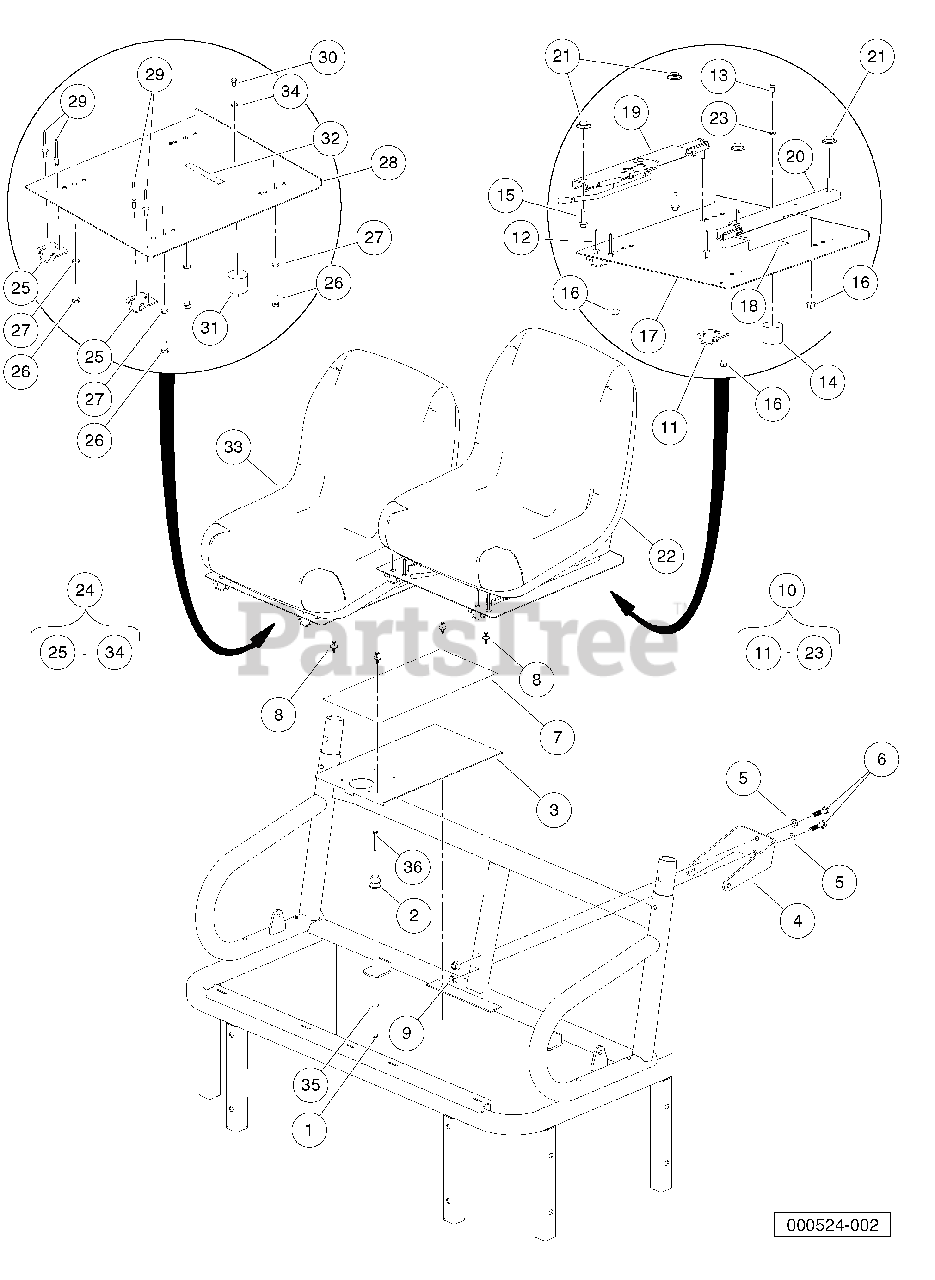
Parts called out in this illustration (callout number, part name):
1	Locknut, M6-1.00 Nylon Insert
2	Seat Holder Base
3	Pan, Center, Closeout
4	Bracket, Seatbelt, Bolt-On
5	Washer, Hard, M10, Zn-Ni/Blk
6	Bolt, M10 X 45, Zn-Ni (Black)
7	Cover, Center Console
8	Rivet, Removable, Tuflok 1/4"
9	Nut, Flanged, M10 x 1.5, Black
10	Asm, Bracket Seat, Adj, Blk
11	Hinge Plate
12	Rivet, 1/4 X .438 Blind
13	Screw, 6m-1.00 X 10mm Hex Head
14	Seat Holder Cup
15	Bolt, Flange Head, M8 X 30.0
16	Nut,m8,all Metal Lock
17	Pan, Seat, Driver Asm
18	Decal, Hot Surface Warning
19	Adjuster, Forward/Aft
20	Adjuster, Slider
21	Washer, Bell
22	Seat, Bucket, Black
23	Lockwasher, 1/4 Helical Split
24	Asm, Bracket Seat, Passenger, Blk
25	Hinge Plate
26	Screw, M8-125 X 22 Hex-Head
27	Lockwasher, 8mm Split
28	Pan, Seat, Passenger
29	Rivet, 1/4 X .438 Blind
30	Screw, 6m-1.00 X 10mm Hex Head
31	Seat Holder Cup
32	Decal, Hot Surface Warning
33	Seat, Bucket, Black
34	Lockwasher, 1/4 Helical Split
35	Washer, 1/4 Type A Narrow Flat
36	Bolt, M6 X 1 X 45
